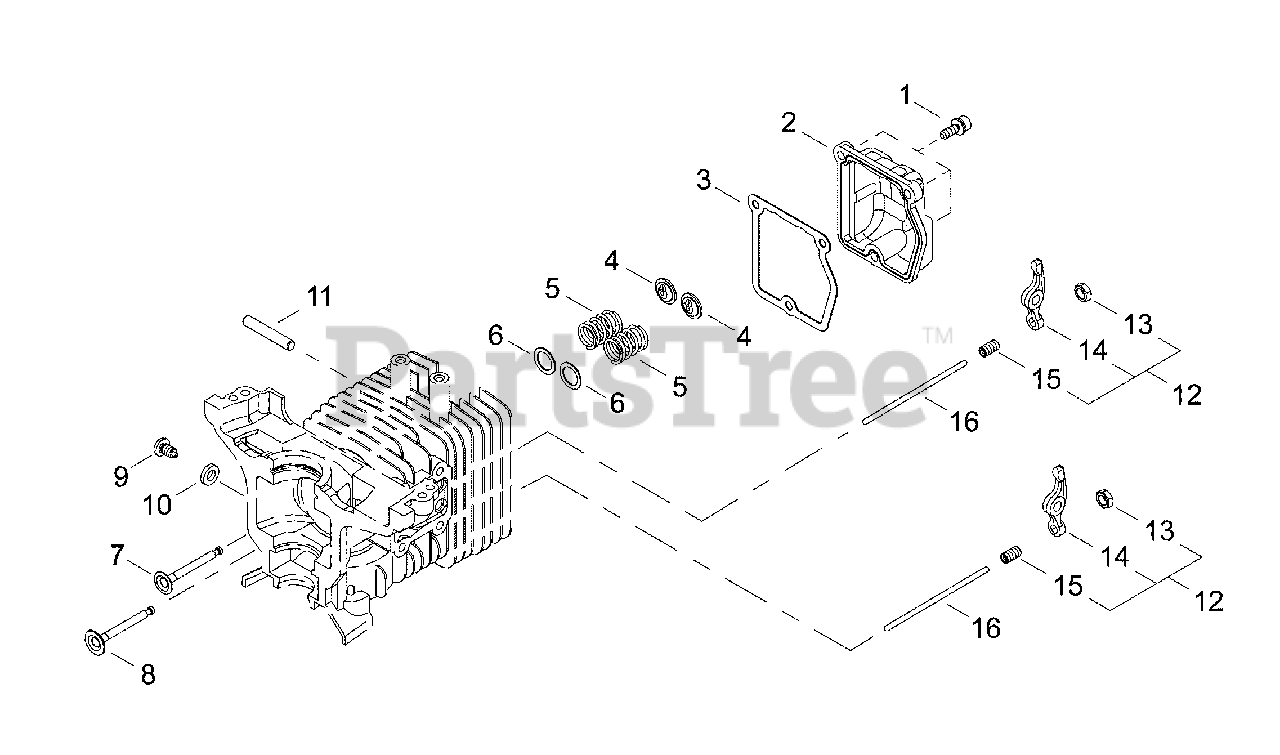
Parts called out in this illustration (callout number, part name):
1	SCREW - 4X12
2	COVER, ROCKER ARM
3	GASKET
4	RETAINER, VALVE
5	SPRING, VALVE
6	WASHER, VALVE - 9
7	VALVE, EXHAUST
8	VALVE, INTAKE
9	SCREW - 5
10	WASHER
11	SHAFT, ROCKER ARM - 5X31.8
12	ROCKER ARM ASSY
13	LOCKNUT, ADJUSTER
14	ARM, ROCKER
15	SCREW, ADJUST
16	PUSHROD
